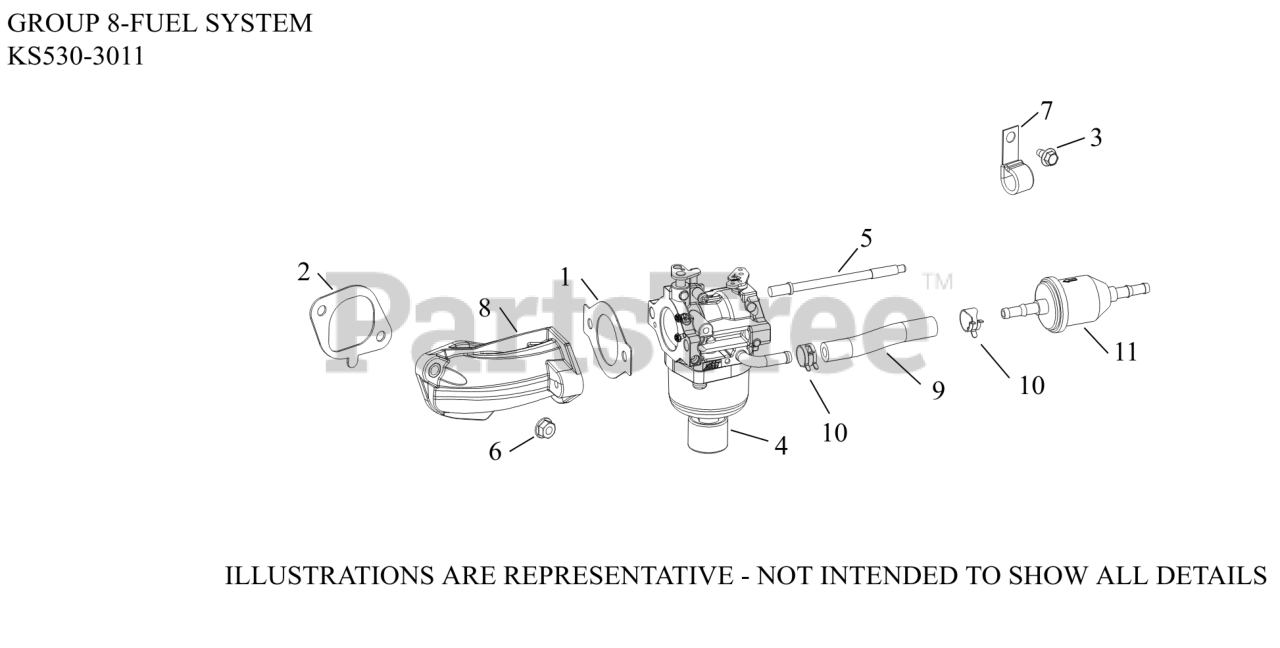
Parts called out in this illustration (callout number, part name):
1	GASKET, CARBURETOR (THROTTLE)
2	GASKET, INTAKE MANIFOLD
3	SCREW, THREAD FORMING
4	KIT,CARB(NIKKI)
5	STUD, CARBURETOR
6	NUT, FLG M6X1.0
7	CLIP, CABLE
8	MANIFOLD, INTAKE ASSEMBLY
9	HOSE,LW PERM.FUEL 24.00"-USE 25 111 81-S
10	SPRING CLAMP, HOSE
11	FILTER,FUEL 75 MICRON (GRAVTY FEED)
NI	HIGH ALTITUDE KIT (5000 FT)
NI	KIT, OVERHAUL
NI	KIT, CHOKE SHAFT
NI	KIT, O-RING
NI	KIT, SOLENOID (NIKKI)
NI	KIT, BOWL WITH O-RINGS
NI	KIT, FLOAT AND INLET NEEDLE FOR GRAVITY
NI	KIT, THROTTLE SHAFT
